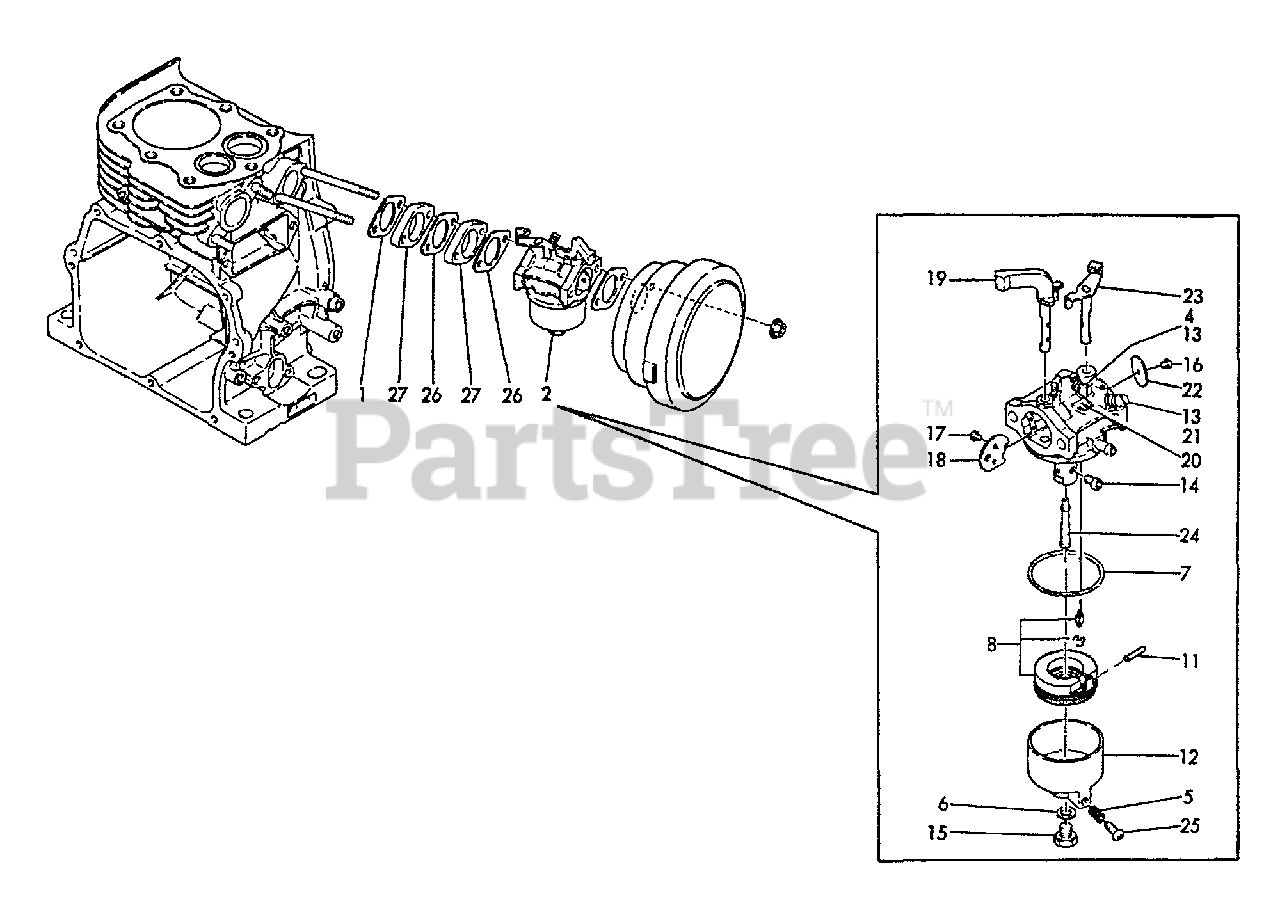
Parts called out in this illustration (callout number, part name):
1	GASKET, EXHAUST
2	CARBURETOR
4	SCREW, THROTTLE
6	WASHER
7	GASKET
8	NEEDLE ASSY - RUBBER
11	PIN
12	BODY, FLOAT CHAMBER
14	JET, MAIN
15	BOLT
16	SCREW
17	SCREW -- TAPPING
18	VALVE, CHOKE
19	SHAFT, CHOKE
20	JET, PILOT
21	SCREW, PILOT
22	VALVE, THROTTLE
23	SHAFT, THROTTLE
24	NOZZLE, MAIN
25	SCREW
26	GASKET, INTAKE
27	INSULATOR, INTAKE
